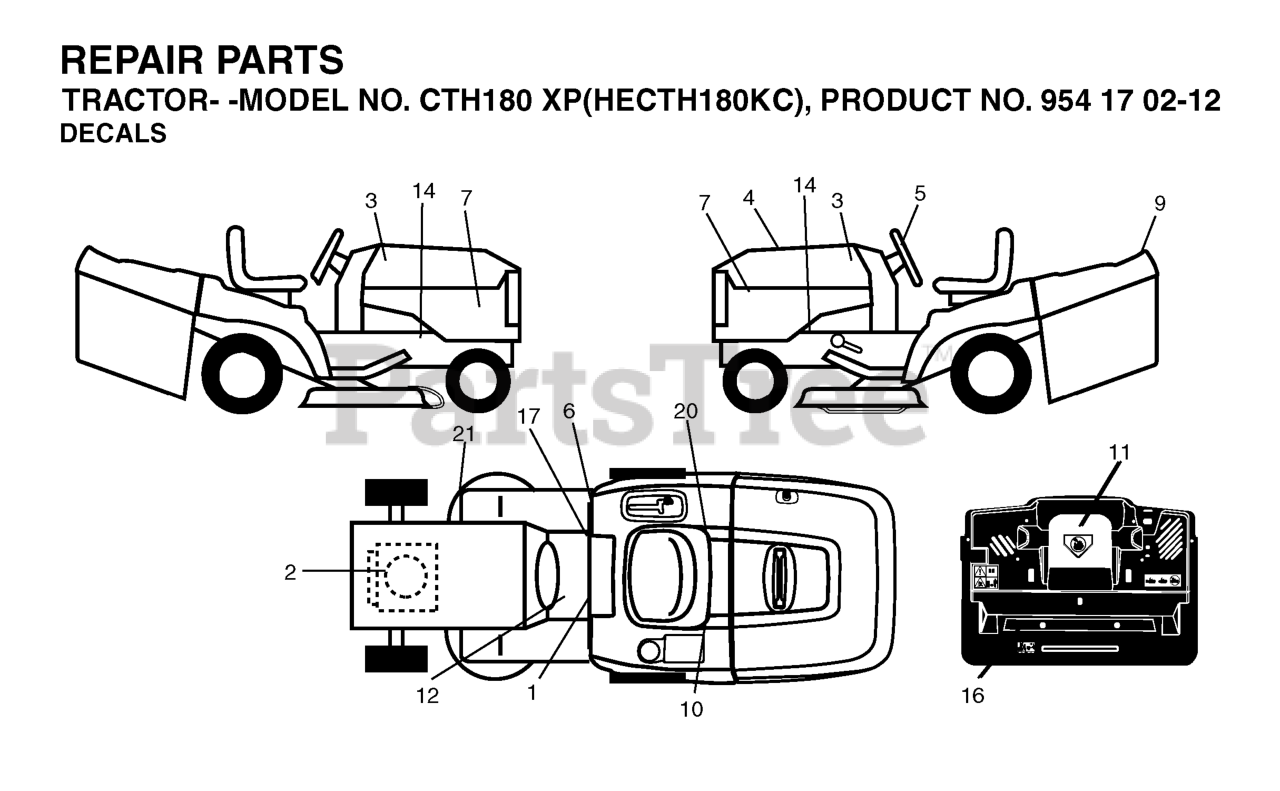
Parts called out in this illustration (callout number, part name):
1	DECAL READ OWNER'S MAN SYMS
2	DECAL ENGINE
5	DECAL.STEERING.HUSQ.BLUE
6	Decal, Fender 100 DB/CE
7	DECAL.HOOD.HUSQVARNA.INTERNATI
10	DECAL BTRY SYMBOLS
11	DECAL.INTERNATIONL.CUTFINGER
12	DECAL
16	DECAL
17	DECAL PARK BRAKE
20	DECAL.BYPASS.FENDER.CRD.LT.YT
